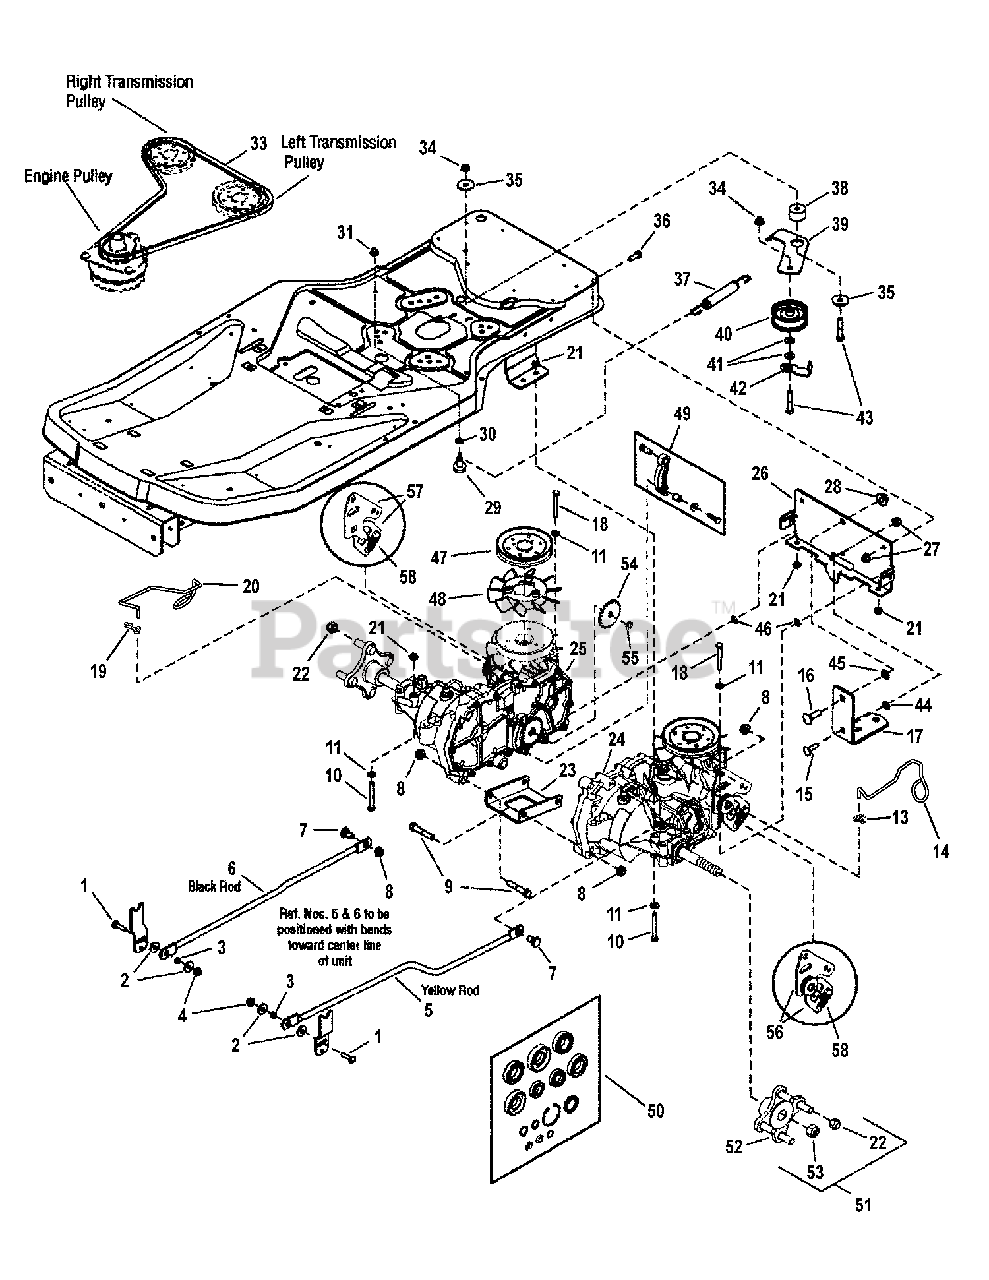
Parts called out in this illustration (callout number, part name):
1	BOLT, 5/16-18 x 1-1/4" Round Head Short Square Neck GR5 Black
2	WASHER, 5/16" Flat (.341 I.D. x 1.00 O.D. x .13 Thick) Black
3	SPACER, .323 I.D. x .500 O.D. x 0.270 Long Heat Treated
4	NUT, 5/16-18 Hex Keps Conical Washer Black
5	ROD, Control, LH (.500 Dia. X 27.88 Long) Sears
6	ROD, Control, RH (.500 Dia. X 27.88 Long) Sears
7	SHOULDER BOLT, 7/16-14 x 1.07 Long GR5 Sears
8	NUT, 7/16-14 Hex Flange Lock Two Way Ga Black
9	SCREW, 7/16-14 x 2-1/4" Hex Head Cap, GR8 Black
10	SCREW, 5/16-18 x 2-3/4" Hex Head Cap, GR5 Black
11	WASHER, .312 (.34 I.D. x.75 O.D.)
13	CLIP, Rod End Clevis RH (for .188 Dia. Rod)
14	ROD, Tow Valve LH (.156 Dia. 5.05 Long)
15	BOLT, 3/8-16 x 1-1/4" Round Head Short Square Neck, Black
16	BOLT, 1/2-13 x 1-1/2" Round Head Short Square Neck, GR5 Black
17	DRAWBAR- .250 Thick Sears- Black
18	SCREW, 5/16-18 x 2-1/2" Hex Head Cap, GR5 Black
19	CLIP, Rod End Clevis LH (for .188 Dia. Rod)
20	ROD, Tow Valve RH (.156 Dia. 5.05 Long)
21	NUT, 5/16-18 Hex Flange Lock, Small - Black
22	NUT, 1/2-20, (for Wheel Bolt) Silver
23	SUPPORT, Transmission Center Sears -Black
24	TRANSMISSION- Hydro Gear EZT LH (ZC-AHBB-2A7B-1DPX)
25	TRANSMISSION- Hydro Gear EZT RH (ZC-DHBB-2A7C-1DPX)
26	SUPPORT, Transmission Rear Sears -Black
27	NUT, 3/8-16 Hex Flange Nyloc
28	NUT, 1/2-13 Hex Flange Nyloc
29	SHOULDER BOLT, 5/16-18 GR5
30	WASHER, 5/16 Flat (.341 I.D. x .87 O.D. X .06 Thick) Black
31	NUT, 5/16-18 Hex Flange Lock Large Black
33	* V-BELT, Transmission Drive (HA Sect. 54.40 Effective Length)
34	NUT, 3/8-16 Hex Flange Lock Two Way Ga Black
35	WASHER
36	SCREW, 3/8-16 x 1" Hex Head Cap, GR5 Black
37	SPRING, Extension
38	SPACER (.387 I.D. x 1.50 O.D. x 1.04 Long (Powdered Metal) Yellow
39	ARM, Idler (Transmission Drive) 7 Ga Sears Black
40	PULLEY, Idler
41	WASHER, .375 Flat (.41 I.D. x .87 O.D.)
43	SCREW, 3/8-16 x 2" Hex Head Cap, GR5
44	NUT, Push Pal, 3/8"
45	NUT, Push Pal, 1/2"
46	NUT, Push Pal .312 Dia. Thread .625 O.D. Black
47	PULLEY, 4-1/2" Transmission
48	FAN, 6" Transmission
49	BRAKE ARM & PIN, Hydro-Gear
50	KIT, Hydro Seal
51	KIT, Hub Replacement
52	HUB, EZT Transmission
53	NUT, EZT Transmission
54	GEAR, Parking Brake, Transmission
55	CLIP, E Transmission Parking Brake
56	KIT, L.H. Control Arm
57	KIT, R.H. Control Arm
58	SPRING, Extension (Used on Hydro-Gear P/N ZC-AHBB-2A7B-1DPX and ZC-AHBB-2A7B-1DPX)
